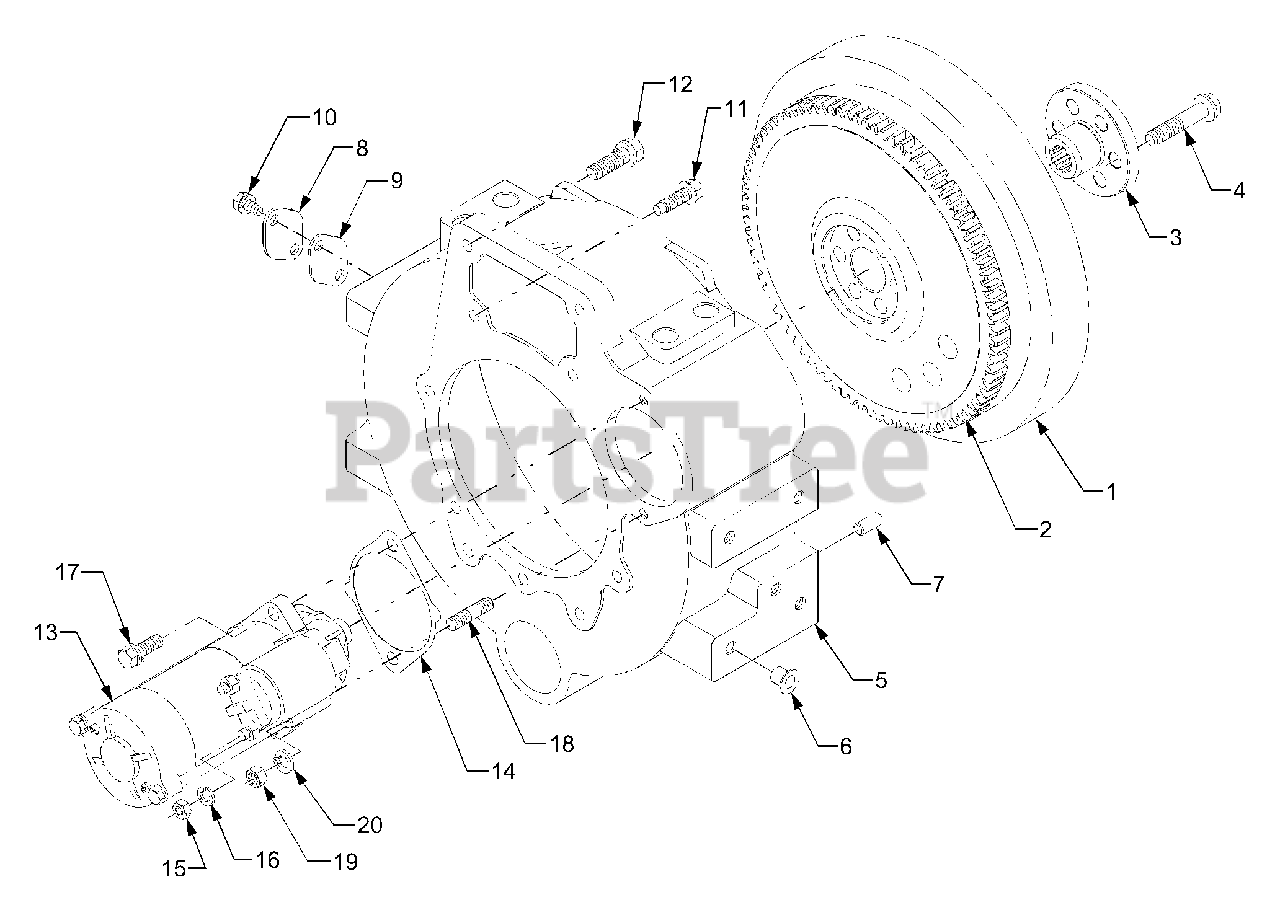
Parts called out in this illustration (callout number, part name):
1	Flywheel Ass'y
4	Bolt, Flywheel
5	Housing, Flywheel
7	Pin, Straight
8	Cover, Timing Mark
9	Gasket, Cover
13	Starter Motor Ass'y
16	Washer, Spring
20	Washer, Spring
